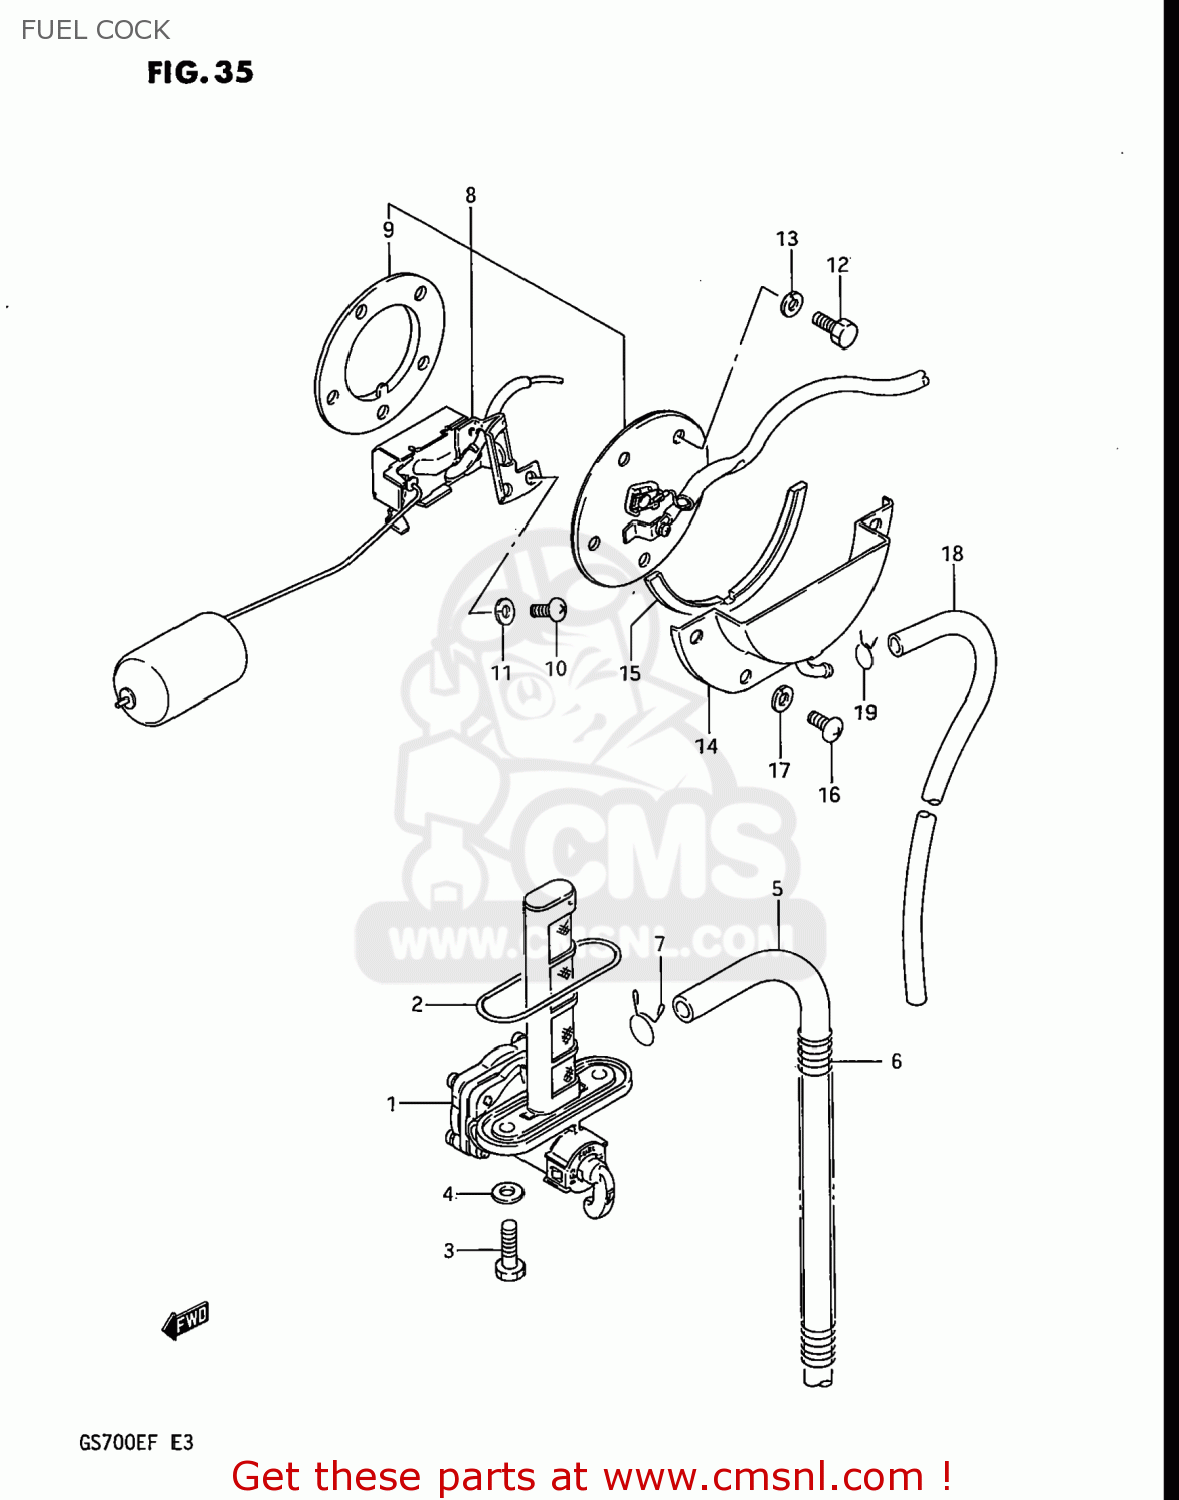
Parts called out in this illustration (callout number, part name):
1	COCK ASSEMBLY,FUEL
2	O RING
3	BOLT(6X20)
4	GASKET
5	HOSE
6	SPRING
7	CLIP
8	GAUGE ASSEMBLY,FUEL LEVEL
9	GASKET,FUEL LEVEL GAUGE (NAS)
10	SCREW 5X10
11	LOCK WASHER
12	BOLT 5X10
13	LOCK WASHER
14	PLATE,FUEL DRAIN
15	GASKET (NAS)
16	SCREW
17	LOCK WASHER
18	HOSE,FUEL
19	CLIP
